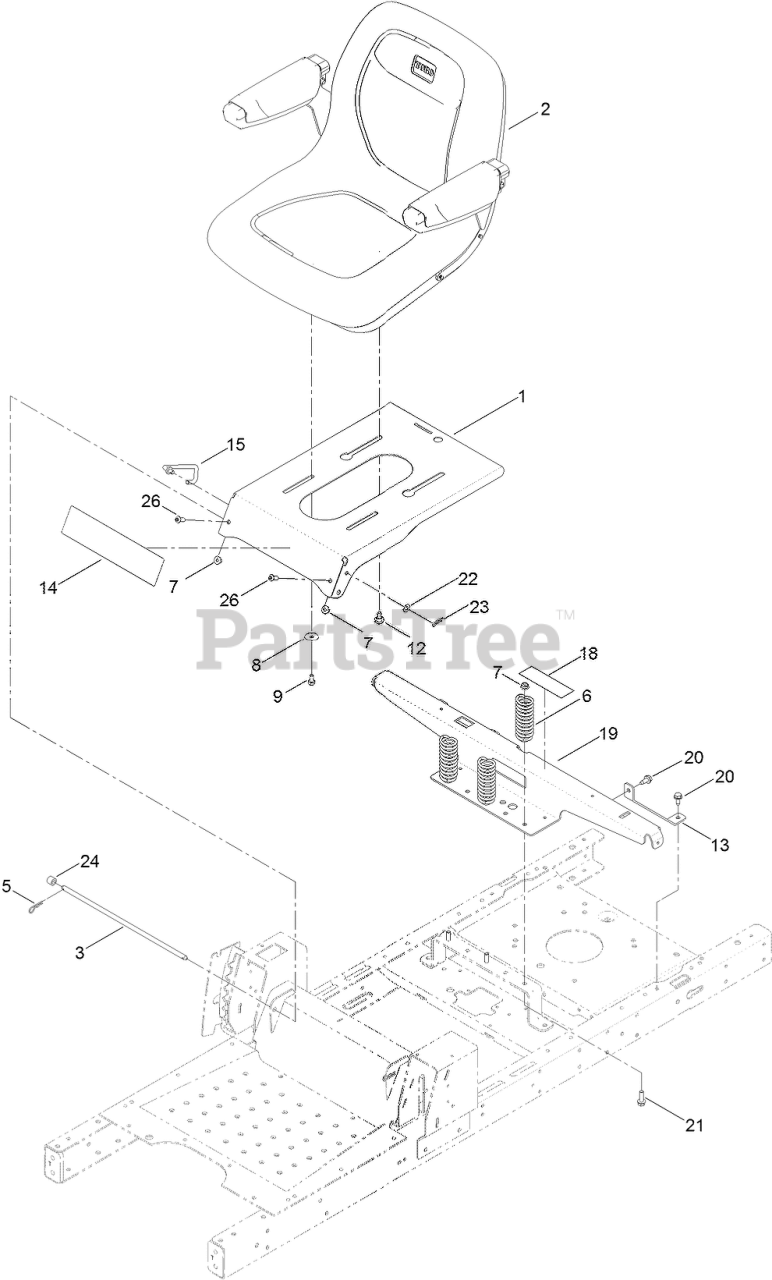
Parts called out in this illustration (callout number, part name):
1	PAN-SEAT
2	SEAT-18 Inch
3	ROD-STOP
5	PIN-COTTER
6	SPRING-COMPRESSION
7	NUT-HF, NI
8	WASHER-PIVOT
9	SCREW-HH
12	BOLT-SHOULDER
13	SUPPORT-TANK, REAR
14	DECAL-TIMECUTTER
15	STOP-SEAT
18	DECAL-SERVICE, CE
19	SUPPORT-POD, WIDE
20	SCREW-HWHTF
21	SCREW-HHF
22	WASHER-PLAIN
23	PIN-COTTER
24	BUSHING-LEVER, LIFT
26	SCREW-HSBH
